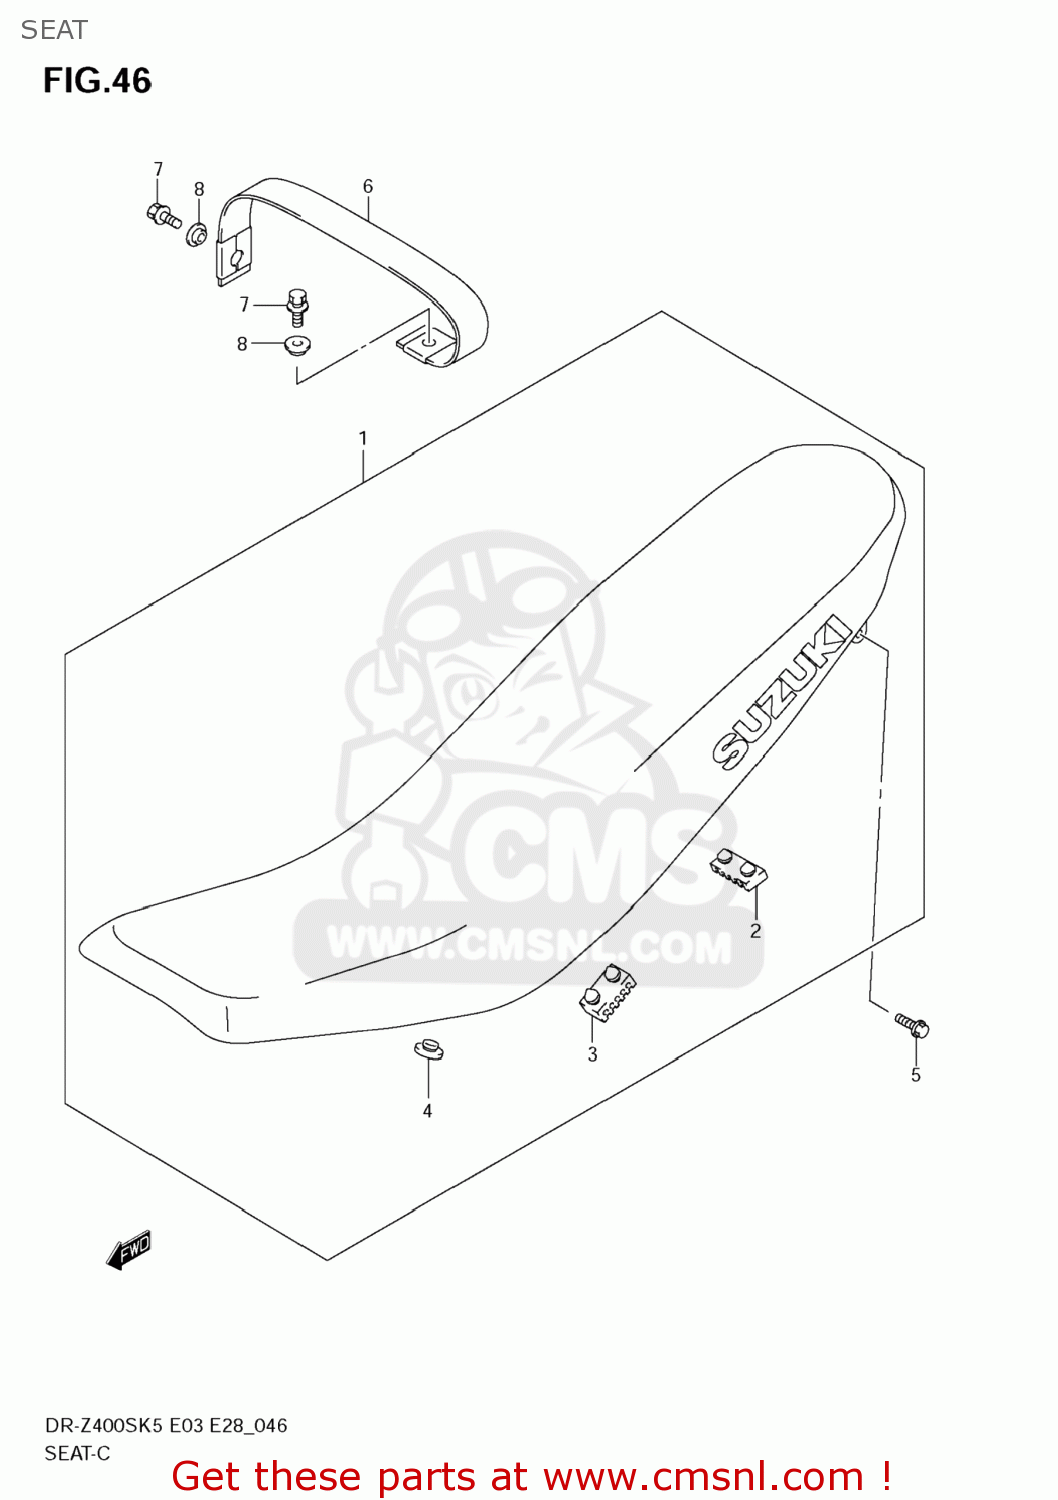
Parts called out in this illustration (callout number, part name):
1	SEAT ASSY
2	CUSHION,SEAT(40X20X6)
3	CUSHION,SEAT(40X20X15)
4	CUSHION
5	BOLT
6	BAND ASSY,SEAT
7	BOLT(6X25)
8	WASHER
